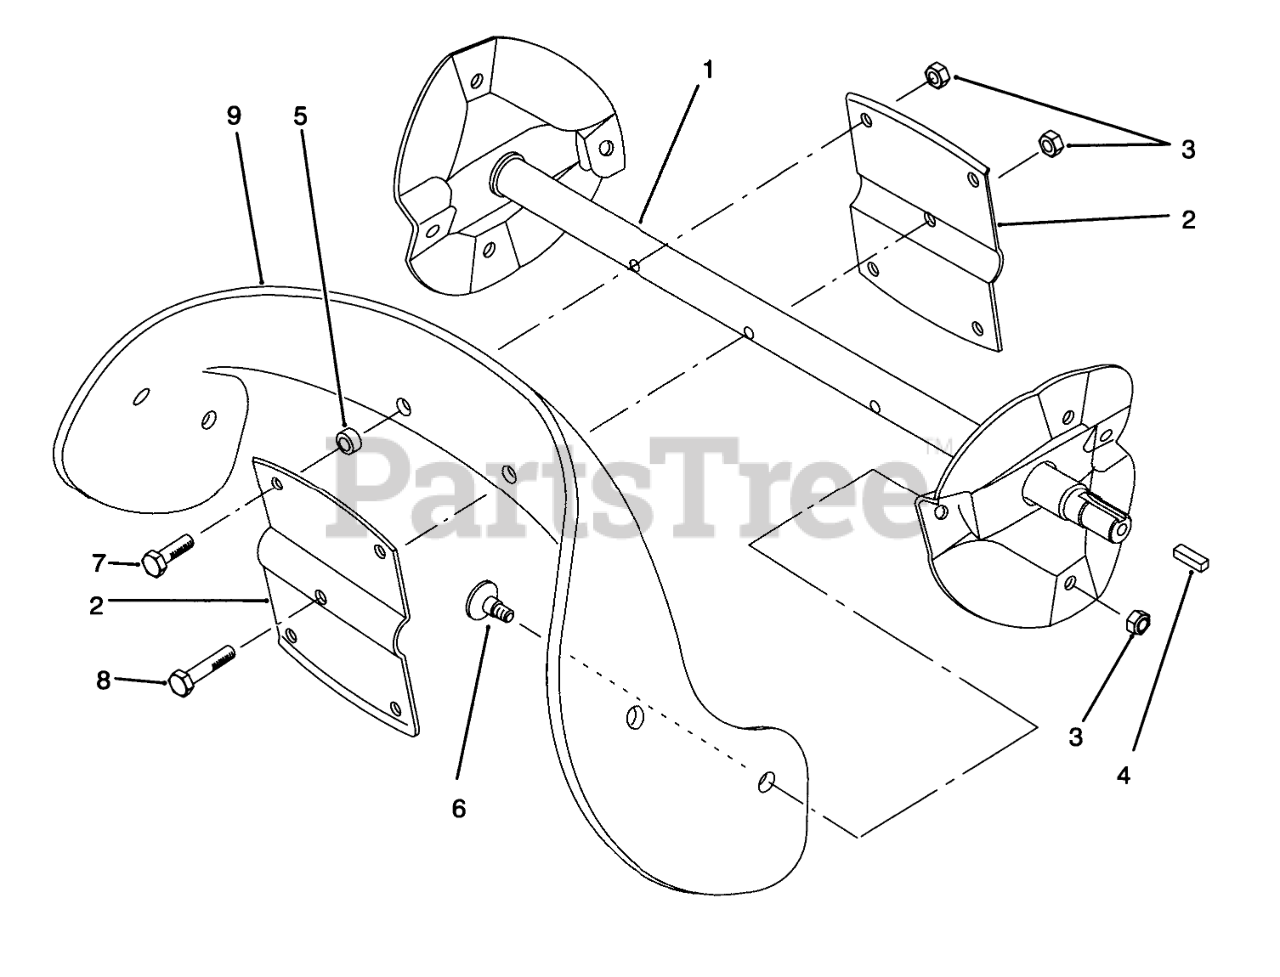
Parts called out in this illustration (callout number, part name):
1	Wa-Rotor
2	Rotor
3	NUT-LOCK, NI
4	KEY-SQUARE
5	SPACER-BLADE, ROTOR
6	SCREW
7	SCREW-HH
8	SCREW-HH
9	Blade-Rotor
